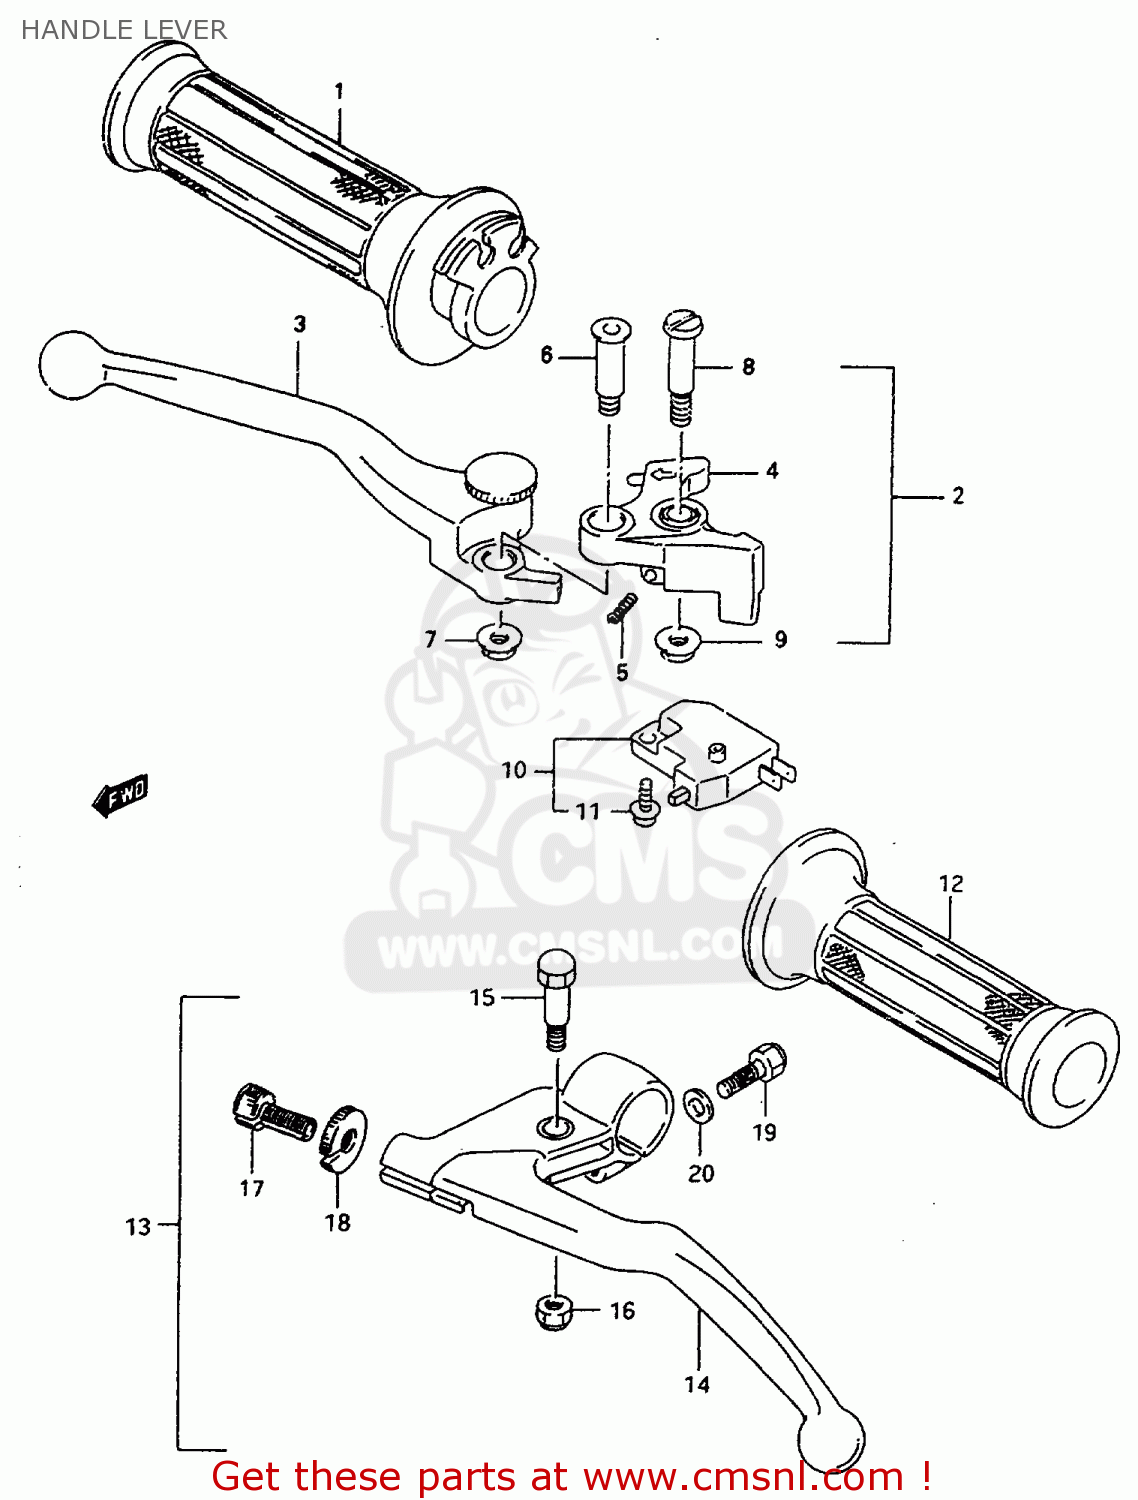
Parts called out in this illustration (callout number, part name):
1	GRIP,THROTTLE
2	LEVER ASSEMBLY,BRAKE
3	LEVER,ADJUST
4	KNOCKER
5	SPRING
6	BOLT,LEVER
7	NUT
8	BOLT,LEVER PIVOT
9	NUT
10	SWITCH ASSEMBLY,STOP
11	SCREW
12	GRIP,L
13	LEVER ASSY,CLUTCH
14	LEVER,CLUTCH
15	BOLT,LEVER PIVOT
16	NUT
17	ADJUSTER,CABLE
18	NUT,CABLE ADJUSTER LOCK
19	BOLT
20	WASHER
